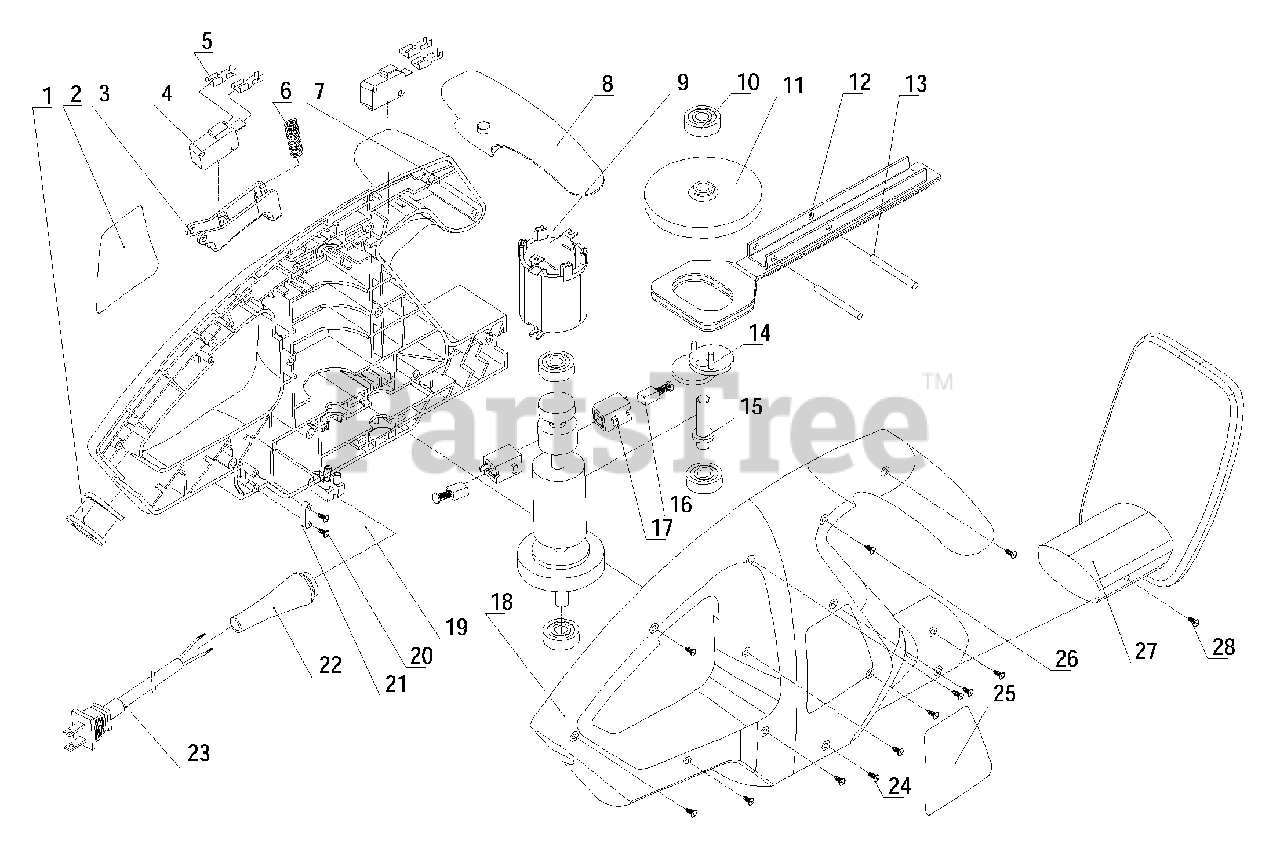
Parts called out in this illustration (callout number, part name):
2	LABEL (L)
7	HOUSING (L)
9	FIELD ASS'Y
12	16" BLADE
14	ECCENTRIC SHAFT
15	OUTPUT SHAFT
17	BRUSH HOLDER
18	HOUSING (R)
19	TERMINAL BLOCK
21	STRAIN RELIEF
22	CORD GUARD
23	POWER CORD
25	LABEL (R)
